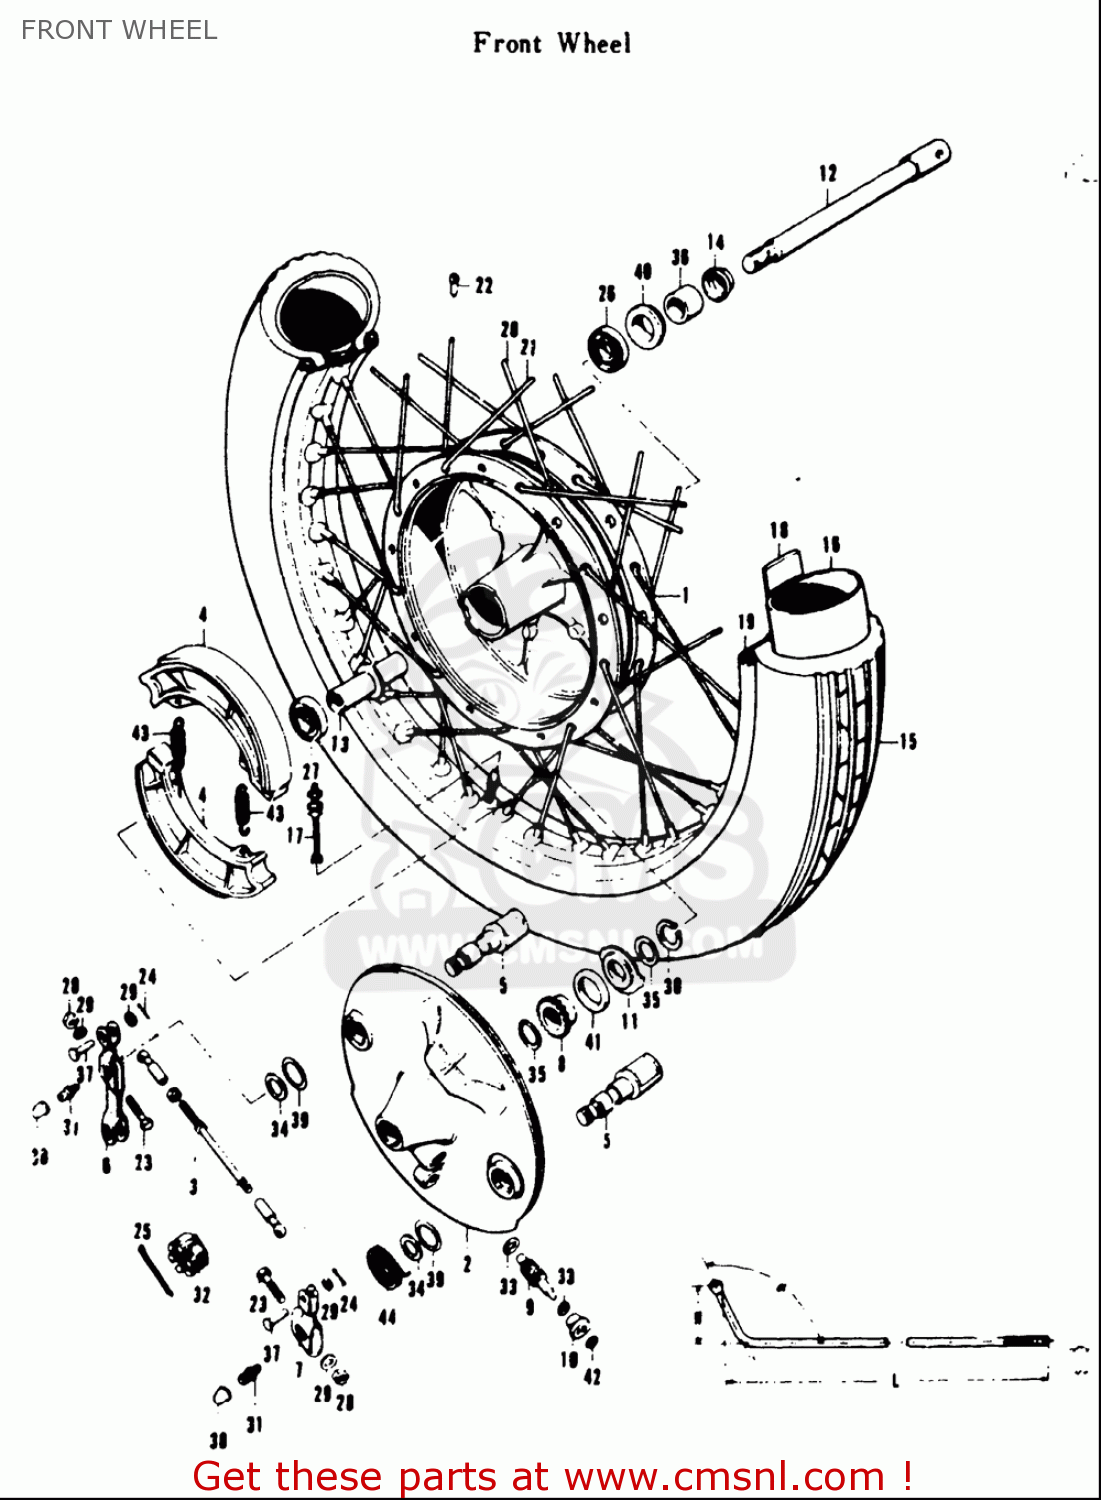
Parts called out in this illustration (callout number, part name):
9	PINION,SPEEDOMETER
10	BUSHING,SPEEDOMETER PINION
11	DRIVER,SPEEDOMETER GEAR
13	SPACER,FRONT HUB BEARING
15	TIRE,FR(2.75-18)
18	PROTECTOR,INNER TUBE
23	BOLT(6X31)
24	PIN 12X10
26	BEARING
27	BEARING
28	NUT
29	WASHER
30	CIRCLIP
31	NIPPLE
32	NUT
33	WASHER(5.1X9X0.4)
34	WASHER(15.5X24X1.6)
35	WASHER(22.5X27X1)
36	SPACER
39	O RING(D:2.4,ID:14.8)
41	SEAL,OIL(26X38X4)
42	SEAL,OIL(6X10X3)
44	SPRING
